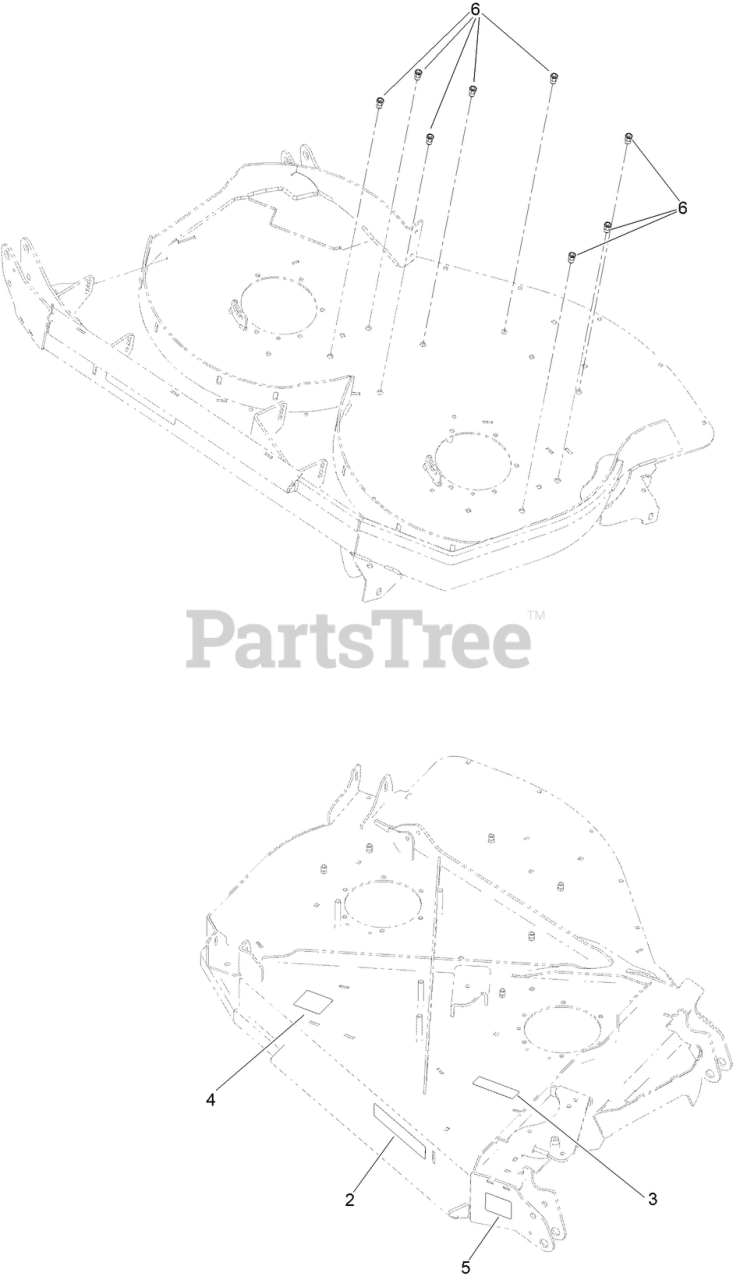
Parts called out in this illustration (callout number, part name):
2	DECAL-TURBO FORCE 144
3	DECAL-COVER, MISSING
4	DECAL-DANGER, THROWN OBJECT
5	DECAL-WARNING, PINCH POINT
6	NUT-CLINCH,HEX
